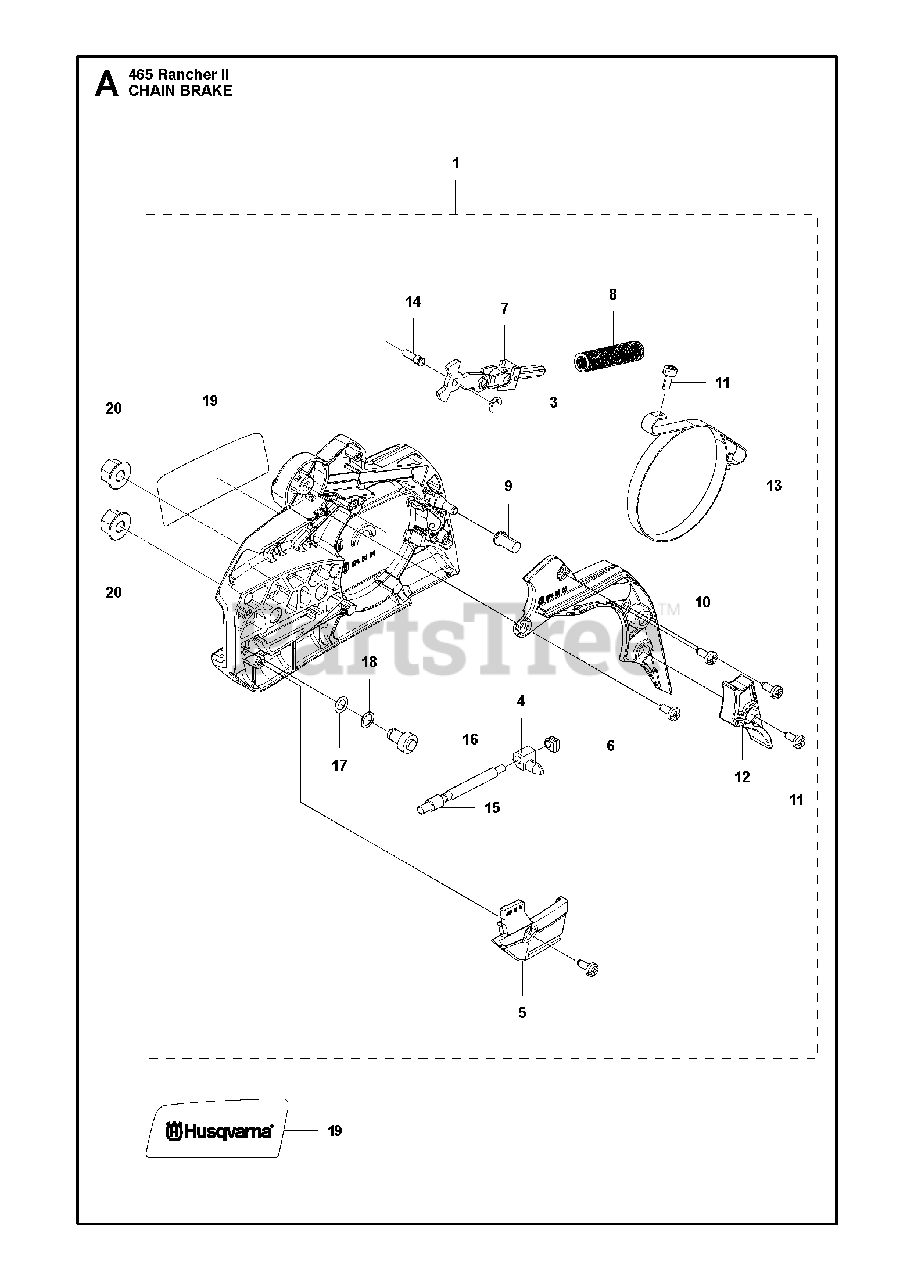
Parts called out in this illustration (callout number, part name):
1	CLUTCH COVER ASSY
3	E-RING 4
4	PAWL
5	CHAIN GUIDE
6	SLEEVE
7	JOINT
8	SPRING
9	SLEEVE
10	COVER LID
11	SCREW
12	WEAR PROTECTION
13	BRAKE BAND
14	PIN
15	WORM SCREW
16	WORM WHEEL
17	O-RING
18	WASHER
19	DECAL, CLUTCH COVER
20	NUT M8 FLANGE
